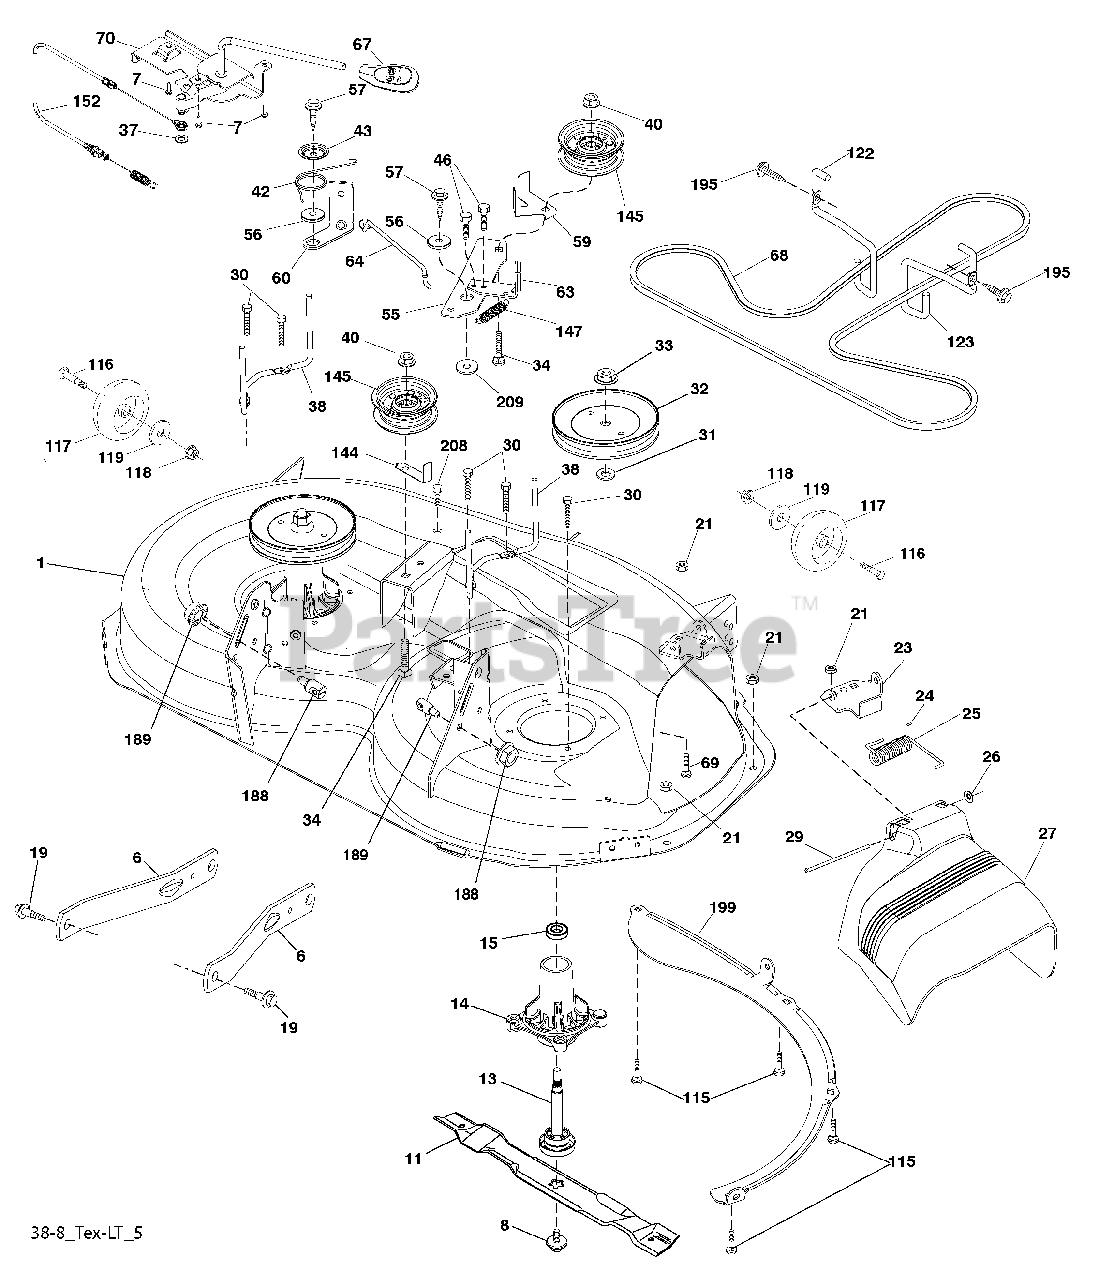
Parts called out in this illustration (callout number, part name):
1	Mower Housing
6	Arm Suspension
7	Screw #10 x 0.750 BOS Thread
8	Bolt/Washer asm 7/16-20 unf
11	Blade 38" 3N1 PREMIUM
13	Shaft Assembly, Mandrel
14	Housing, Mandrel
15	Bearing, Ball, Mandrel
19	Bolt, Shoulder
21	Nut, Crownlock 5/16-18 unc
23	Bracket, Deflector
24	Cap, Sleeve
25	Spring, Torsion, Deflector
27	Shield, Deflector
29	Rod, Hinge
30	Screw Thdrol Rolling Wsh Hd
31	Washer, Spacer
32	Pulley, Mandrel
33	Nut, Toplock, Flanged
34	Bolt Carr Sh. 3/8-16 x 1-1/2 Gr. 5
37	Washer
38	Keeper Belt LH Mandrel
40	Nut, Lock Flg. 3/8-16 unc
42	Spring Torsion Brake
43	Spring Torsion Retainer
46	Screw 1/4-20 x 5/8
55	Arm, Idler
56	Spacer, Retainer
57	Screw 3/8-16 x 1
59	Guard, Tuv Idler
60	Arm Brake Mower LH
63	Arm Brake Mower RH
64	Link Brake
67	Handle Clutch Cable
69	Bolt
70	Clutch Asm Manual
115	Bolt Carr. 5/16-18 x 5/8
116	Bolt, Shoulder
117	Wheel, Gauge
118	Nut Lock 3/8-16 unc
119	Washer 3/8 x 7/8 x 14 Ga.
122	Keeper Belt Engine LH
123	Keeper Belt Engine RH
144	Keeper Belt
145	Pulley Idler
147	Spring Return
152	Manual Clutch Cable
188	Stud Fastener
189	Nut Lock Hex Flange
195	Screw 3/8-16 x 3/4
199	Baffle Vortex
208	Screw Thdrol 3/8-16 x 1/2
209	Washer 13/32 x 2 x 10
